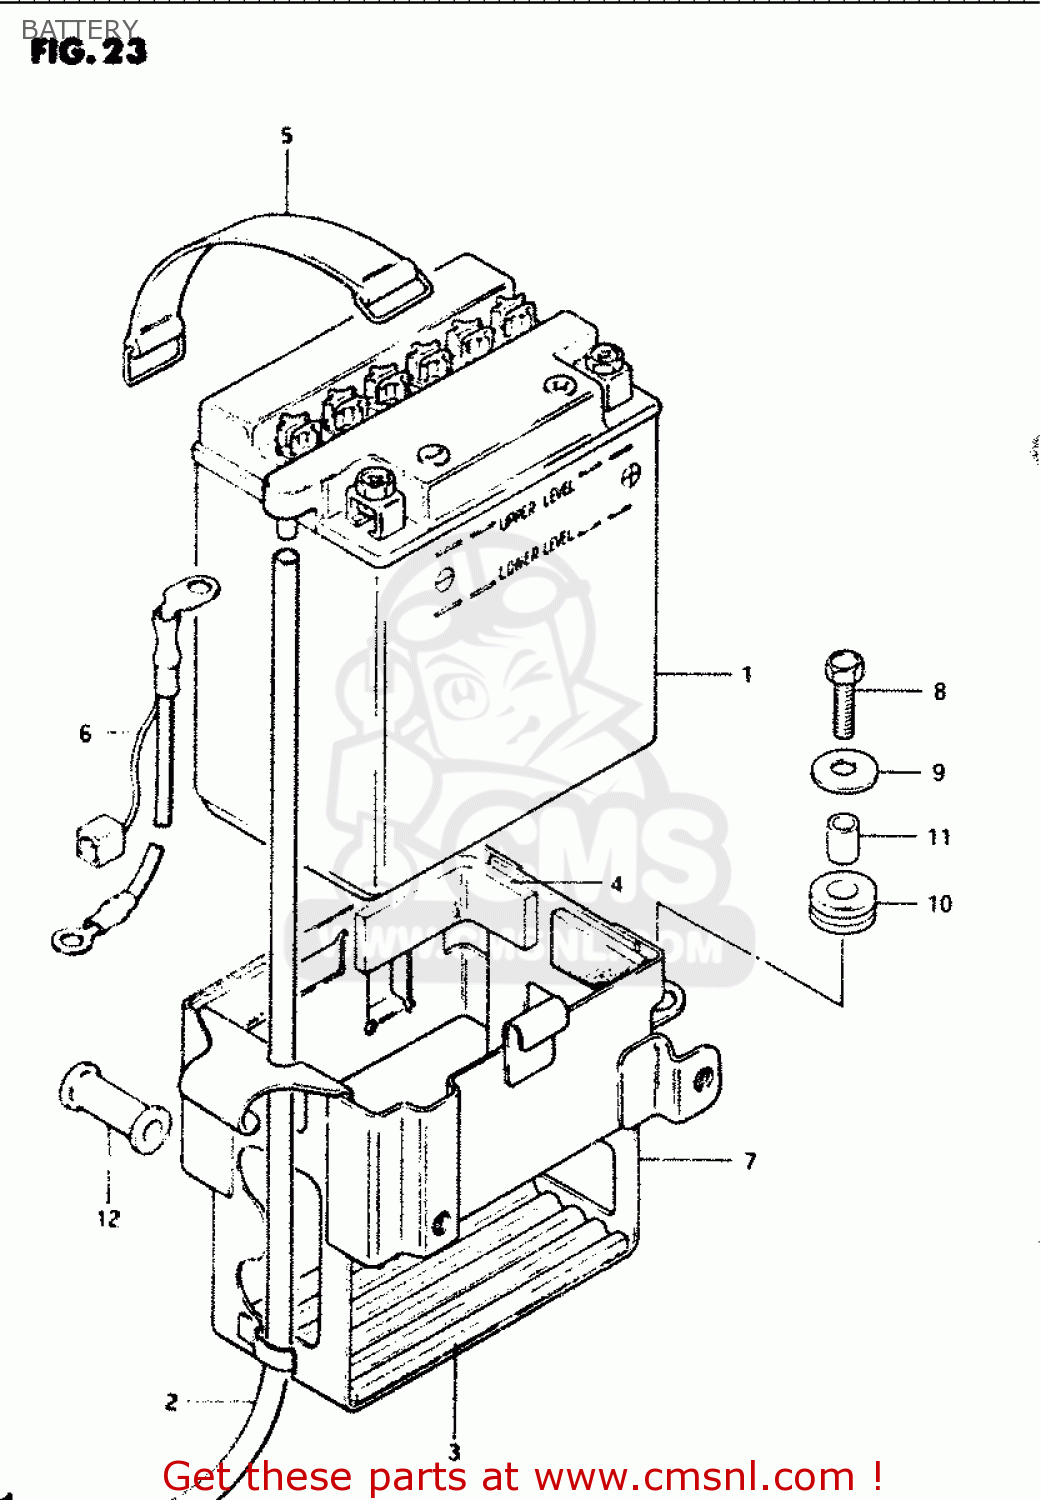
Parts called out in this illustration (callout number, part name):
1	BATTERY ASSY (12V)
2	HOSE,BATTERY EXHAUST
3	PROTECTOR,BATTERY
4	PROTECTOR(170X95X3.0)
5	BAND
6	WIRE,BATTERY MINUS LEAD
7	HOLDER,BATTERY
8	BOLT
9	WASHER(6,5X22X1.6)
10	CUSHION
11	SPACER(6.2X8.3X5.7)
12	CUSHION
